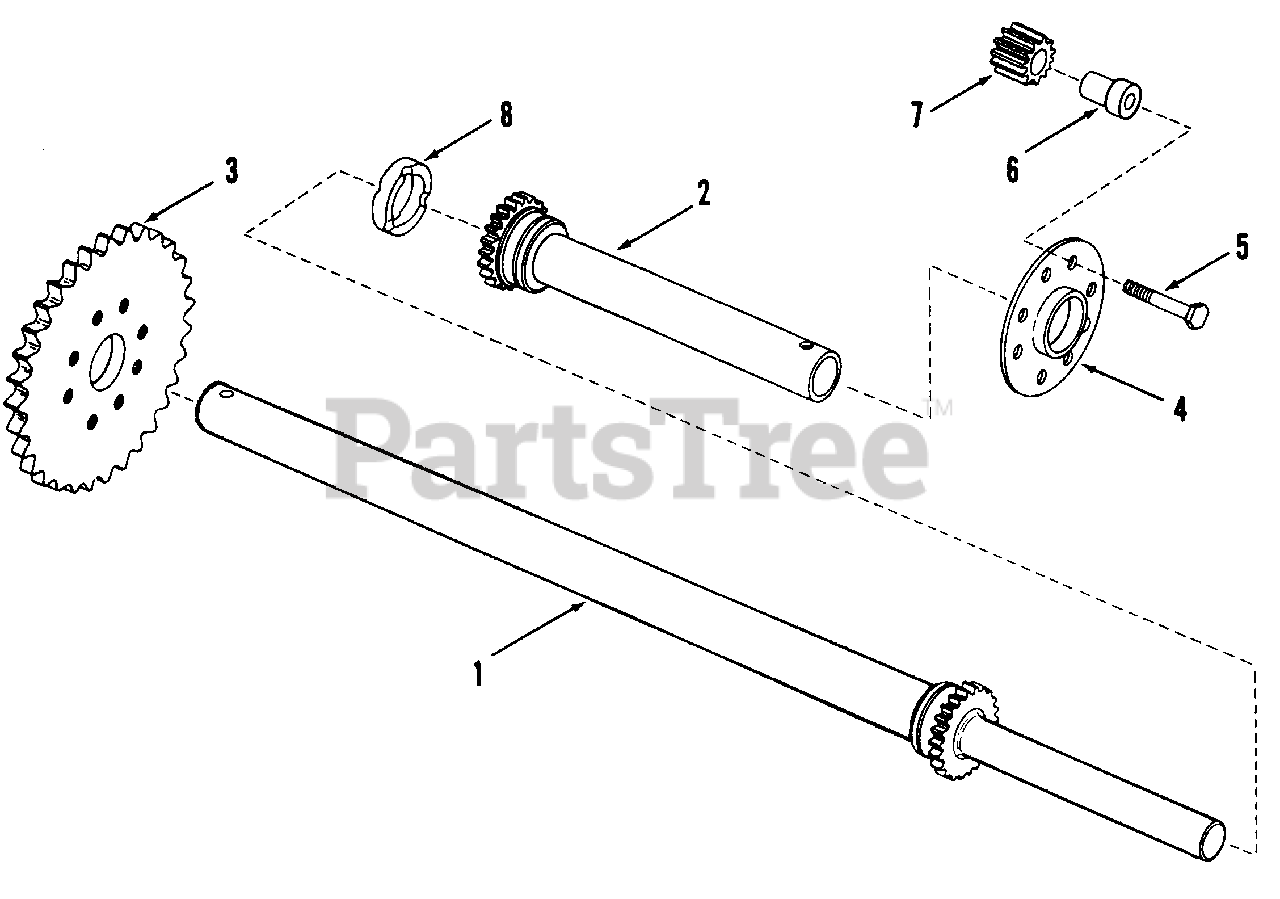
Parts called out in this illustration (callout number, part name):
1	AXLE, Long
2	AXLE, Short
3	SPROCKET, 31 Tooth
4	PLATE, Differential
5	SCREW, 5/16-24 x 1-5/8" Hex Head Cap (Special) Lock, Grade 5
6	SPACER, Pinion
7	PINION GEAR, Differential
8	SPACER, Differential (1.25" ID x .425 Wide)
